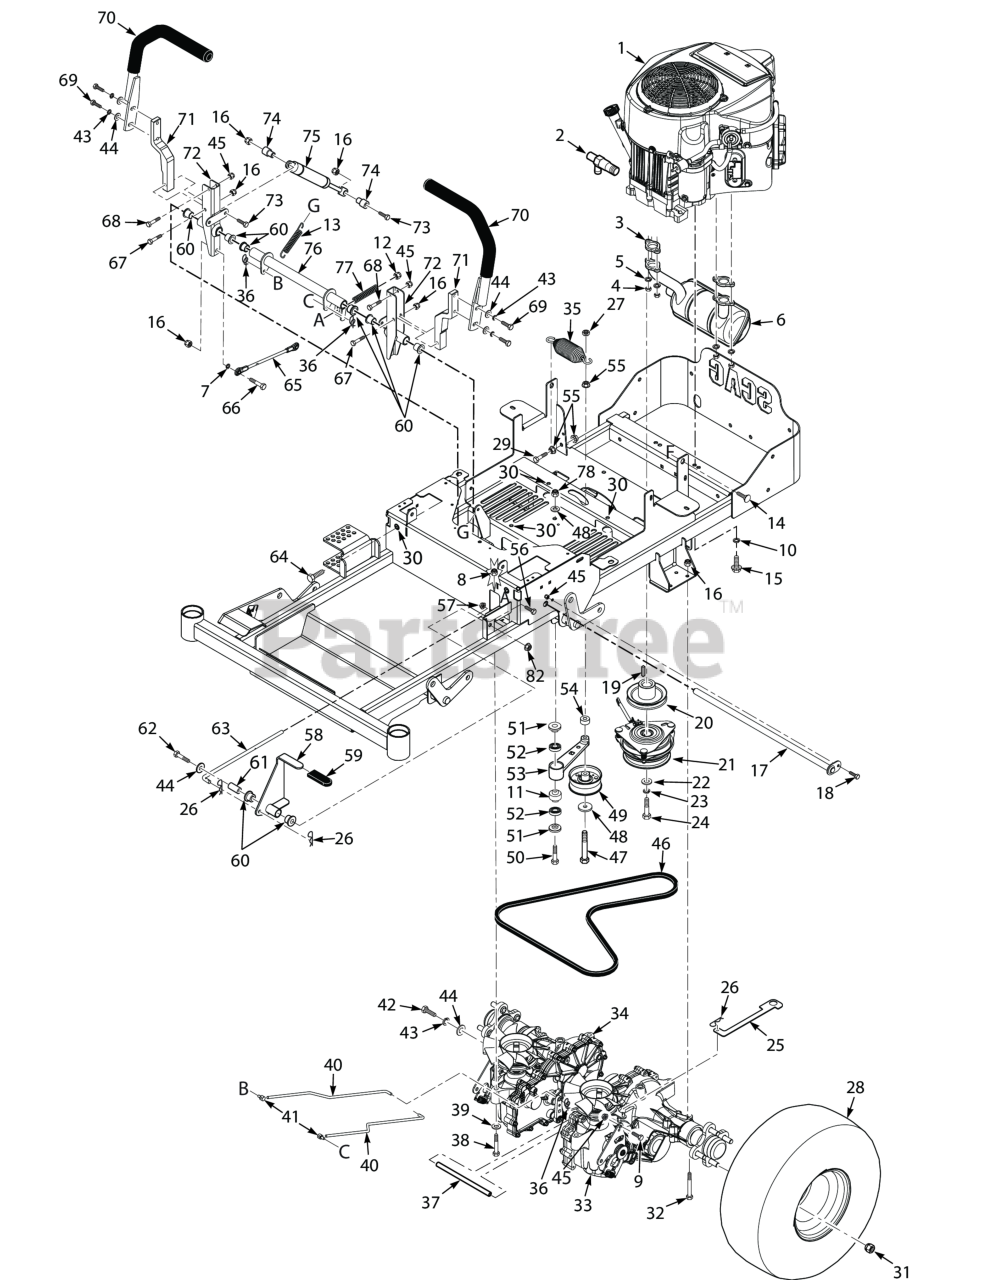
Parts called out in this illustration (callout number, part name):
1	Engine, Kawasaki - FR600V
2	Oil Drain, Kawasaki
3	Gasket, Exhaust
4	Nut, M8 x 1.25 Hex Special
5	Lockwasher, M8 Spring (Kawasaki)
6	Muffler, Kawasaki FR/FS600V
7	Lockwasher, 5/16 (.317 x .586 x .078) Helical Spring
8	Nut, Flange Head Elastic Stop 5/16-18
9	Bolt, Hex Head, 1/4-20 x 1-1/2"
10	Lockwasher, 3/8" Spring, Kawasaki FX / FT & FT-EFI / B&S 32BV
11	Spacer, Bearing
12	Nut, Flange Elastic Stop Nut, 3/8-16
13	Spring, Deck Latch
14	Serr. Fl. Hex Head CPSCR, 1/4-20 x 3/4"
15	Bolt, Hex Head 3/8-16 x 1-1/4", Kawasaki FX / FT & FT-EFI
16	HEX NUT, ELASTIC STOP LOCK, 5/16-18
17	Shaft Weldment, Control Arm
18	BOLT, HEX HEAD, 1/4-20 X 5/8
19	Key, 1/4 x 1/4 x 1.25" Pulley Mtg.
20	Pulley, 4-1/2" - 1" Bore
21	Electric Clutch Assembly
22	Flatwasher, 7/16-.469 x 1.75 x .25 (48, 52)
23	Lockwasher, 7/16� Spring
24	Bolt, Hex Head 7/16-20 x 3¼" w/Patch
25	Lever, Dump Valve
26	HAIR PIN, .08 DIAMETER X 1-3/16"
27	Bolt, Hex Head 3/8-16 x 1" Ser. Flg.
28	WHEEL ASSY, 20 X 10-10
29	Bolt, Hex Head 3/8-16 x 1-1/2" Grade 8 Black
30	Threaded insert, Hex Head (Pressed)
31	Wheel Nut, 1/2-20 x 13/16
32	Bolt, Hex Head, 5/16-18 x 2.75 Zinc.
33	Transaxle, LH- ZT-2800
34	Transaxle, RH- ZT2800
35	Spring, Transmission Drive
36	Pin, Rue Cotter 3/8" Diameter
37	Spacer, Axle
38	BOLT, HEX HEAD, 5/16-18 X 2-1/4
39	Flatwasher, 5/16-.375 x .875 x .083 (35BV & 37BV-EFI)
40	Rod, Brake
41	Joint, Swivel
42	Bolt, Hex Head 3/8-16 x 2-1/4" - 61"
43	Lockwasher, 3/8" Spring, Kawasaki FX / FT & FT-EFI / B&S 32BV
44	Flatwasher, 3/8" Special (.391 x .938 x .105)
45	HEX, NUT, ELASTIC STOP LOCK, 1/4-20
46	Belt, Transmission SZL-36
47	Capscrew, Hex Head 3/8-16 x 3-3/4"
48	Flatwasher, 3/8 (.391 x .938 x .105 HD) Grade 8
49	Pulley, 3-1/2" Dia.
50	Bolt, Hex Head 3/8-16 x 3" - 52"
51	Spacer, Controls
52	BEARINGS, BALL, NEUTRAL RETURN
53	Trans. Idler Arm Assy. (Includes 24, 79)
54	Spacer, Idler Pulley - SFZ61
55	NUT, 3/8-16 SERRATED FLANGE HEX HEAD
56	Bolt, Hex Head 5/16-18 x 1-1/2" (Right Front Engine Mounting, Briggs and Kohler Only)
57	Nut, Flange Elastic Stop Nut, 3/8-16
58	Brake Lever Assembly (INCL 59,60)
59	Grip, Brake Handle
60	Bearing
61	Pivot, Brake Lever
62	Capscrew, Hex Head 3/8-16 x 2-1/2"
63	Rod, Upper Brake Linkage
64	Bolt, Hex Head 3/8-16 x 3.0
65	Linkage Assembly, Steering
66	Bolt, 5/16 - 18 x 1 - 1/4" Hex Head
67	Bolt, Hex Head 5/16-18 x 1-1/2" - Front
68	Bolt, Hex Head, 1/4-20 x 1-1/4"
69	Bolt, Hex Head, 3/8-16 x 1 Gr. 5
70	Handlebar W/ Grip, SZL-36
71	Lever, Control Arm
72	Control Arm Weldment, SZL-36
73	Bolt, Hex Head 5/16-18 x 2-1/2" (x3) (35BV & 37BV-EFI)
74	Spacer, Pump Dampener
75	Damper, Steering
76	Bellcrank Assembly, Brake
77	Spring, Brake
78	HEX NUT, ELASTIC STOP LOCK, 3/8-16
